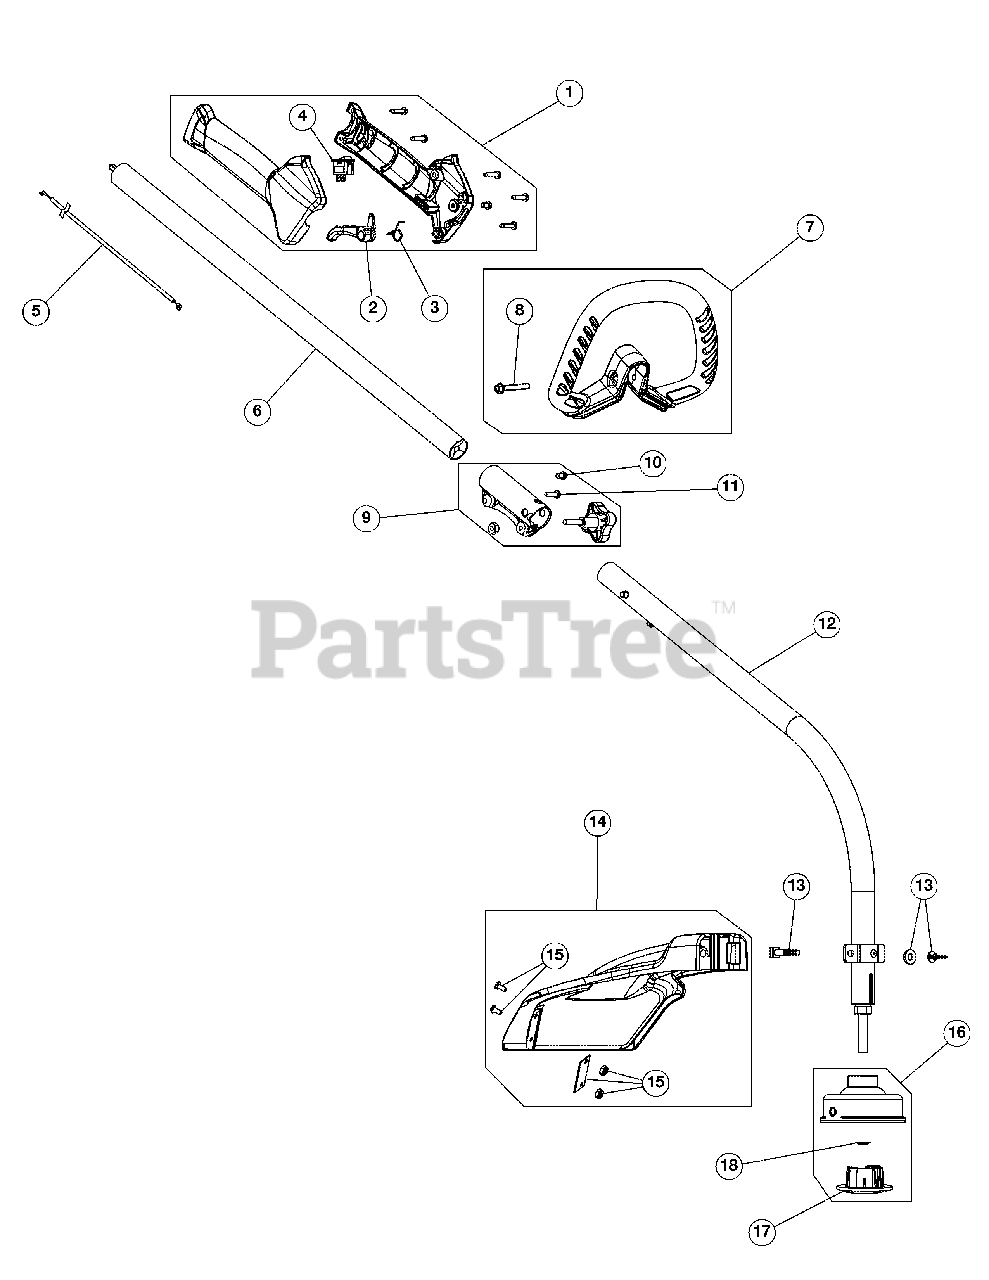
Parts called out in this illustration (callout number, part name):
1	Throttle Housing Assembly (Incl. 2-4)
2	Throttle Trigger
3	Throttle Trigger Spring
4	Switch Assembly
5	Throttle Cable Assembly
6	Upper Drive Shaft Assembly
7	D-Handle Assembly (Incl. 8)
9	Split Boom Coupler (Incl. 10-11)
10	Coupler Anti-Rotation Screw
11	Coupler Bolt
12	Lower Drive Shaft Housing
13	Shield Mount Hardware
14	Shield Assembly (Incl. 15)
15	Blade Assembly
16	Cutting Head Assembly (Incl. 17 & 18)
17	Cutting Head Cap
18	Push Nut
